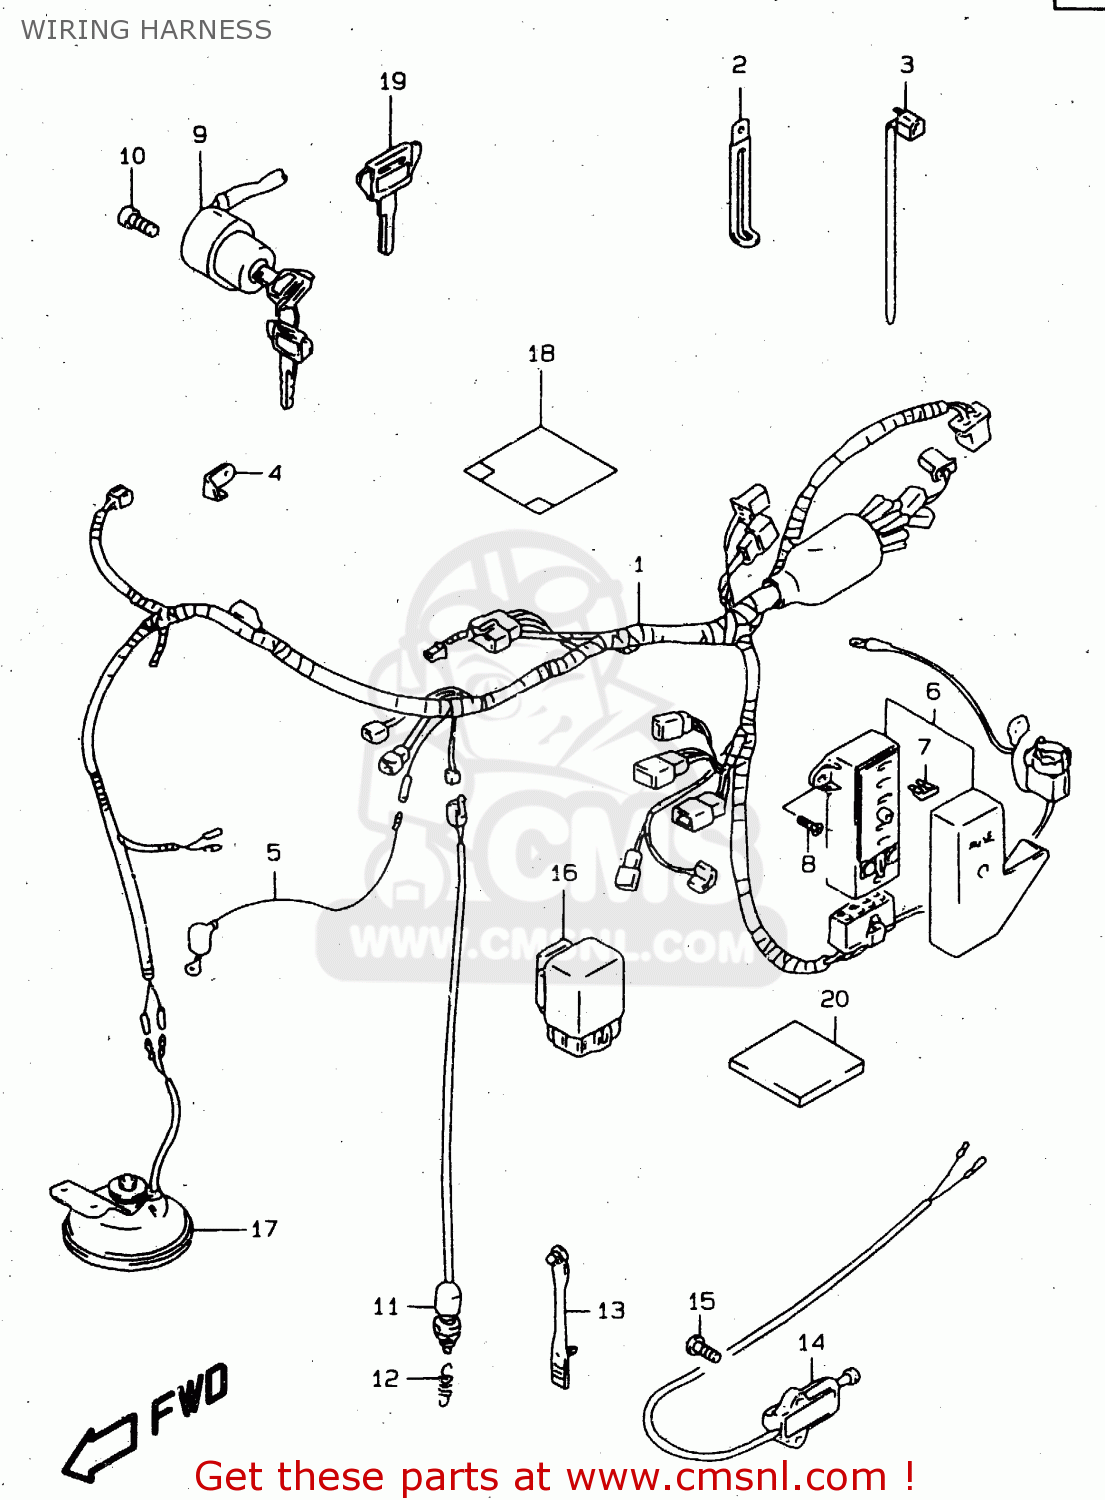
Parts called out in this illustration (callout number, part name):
1	HARNESS,WIRING
2	CLAMP(L:65)
3	CLAMP L:165
4	PLATE,COUPLER HOLDER
5	WIRE,WATER TEMP GAUGE LEAD
6	BOX ASSY,FUSE
7	FUSE(10A)
8	SCREW
9	SWITCH ASSY,IGNITION
10	BOLT
11	SWITCH ASSY,STOP LAMP
12	SPRING
13	CLAMP,L:88
14	SWITCH ASSY,SIDE STAND
15	SCREW
16	RELAY ASSY
17	HORN ASSY
18	COVER,WIRING HARNESS
19	KEY,BLANK(TYPE:C)
20	COVER,HARNESS
